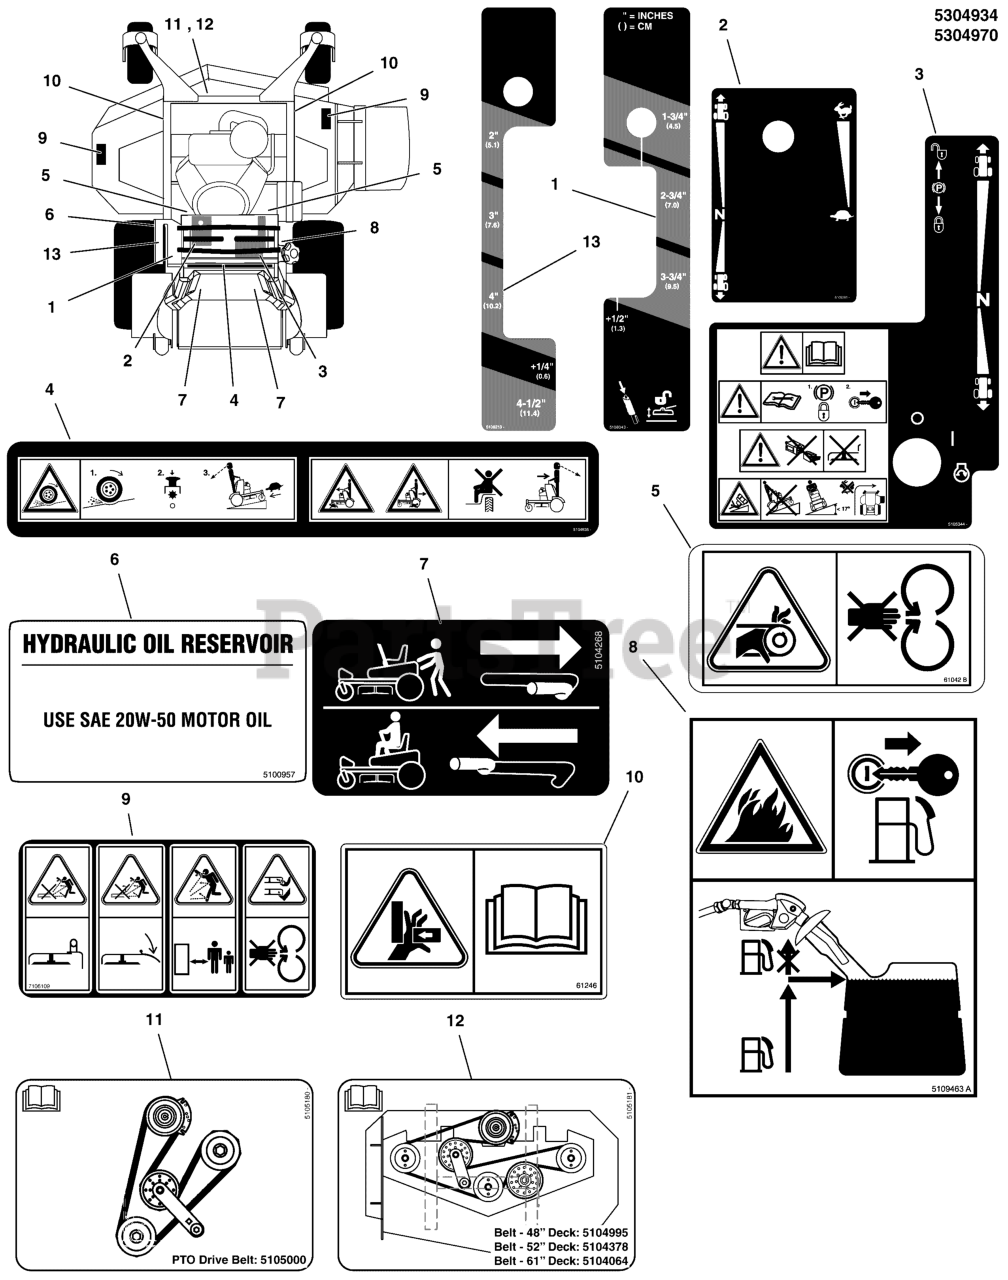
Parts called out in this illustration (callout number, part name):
1	DECAL, CUT HEIGHT, STAND ON, Z1 & SS100
2	DECAL, DASH PANEL, LH, CONTROLS
3	DECAL, DASH PANEL, RH, WRNGS/CNTRLS, CE
4	DECAL, WARNINGS, OPER COMPARTMENT, CE
5	DECAL, CE DANGER, HAND IN BELT
6	DECAL, HYDRAULIC OIL, 20W-50, 1" X 1.44"
7	DECAL, TRANSAXLE RELEASE, WB
8	DECAL, TANK, OVERFILL, CE
9	DECAL, DISCHARGE SAFETY, EXPORT
10	DECAL, Pinch Point, CE
11	DECAL, BELT ROUTING, SRS-36
12	DECAL, BELT ROUTING, SRS-48-52-61
13	DECAL, CUT HEIGHT, SRSZ1
